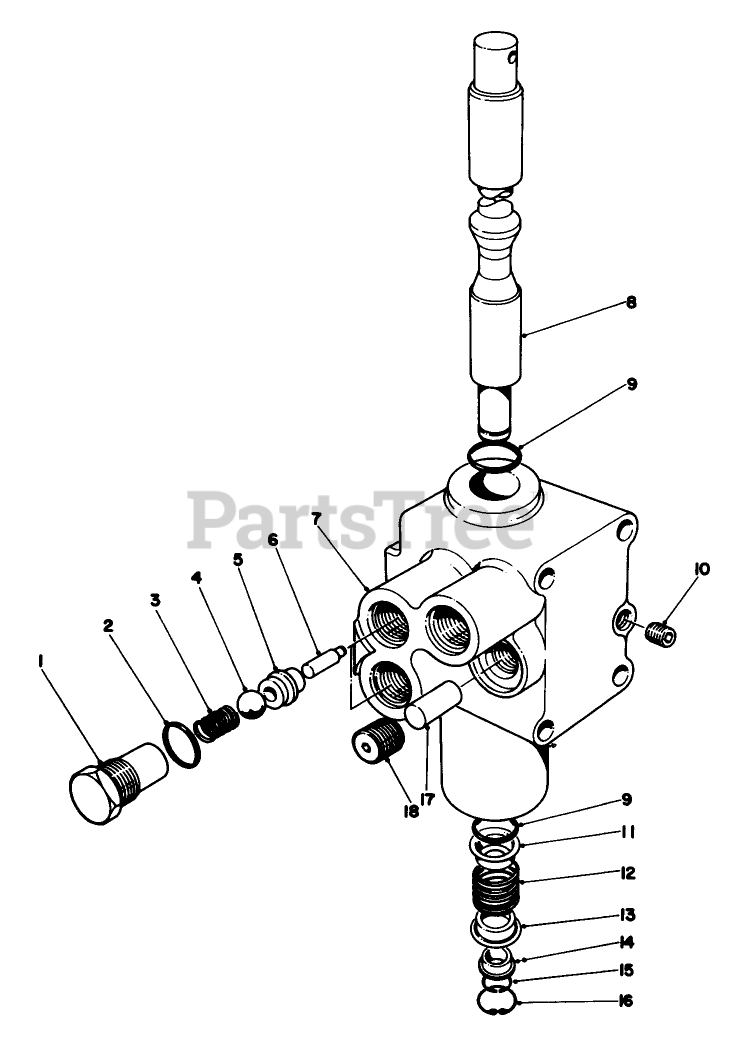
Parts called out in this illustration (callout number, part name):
2	O-RING
3	SPRING
5	SEAT-VALVE
7	Body
8	SPOOL
9	O-RING
11	RETAINER
12	SPRING
13	RETAINER
14	SPACER
15	RING-SNAP
16	RING-SNAP
